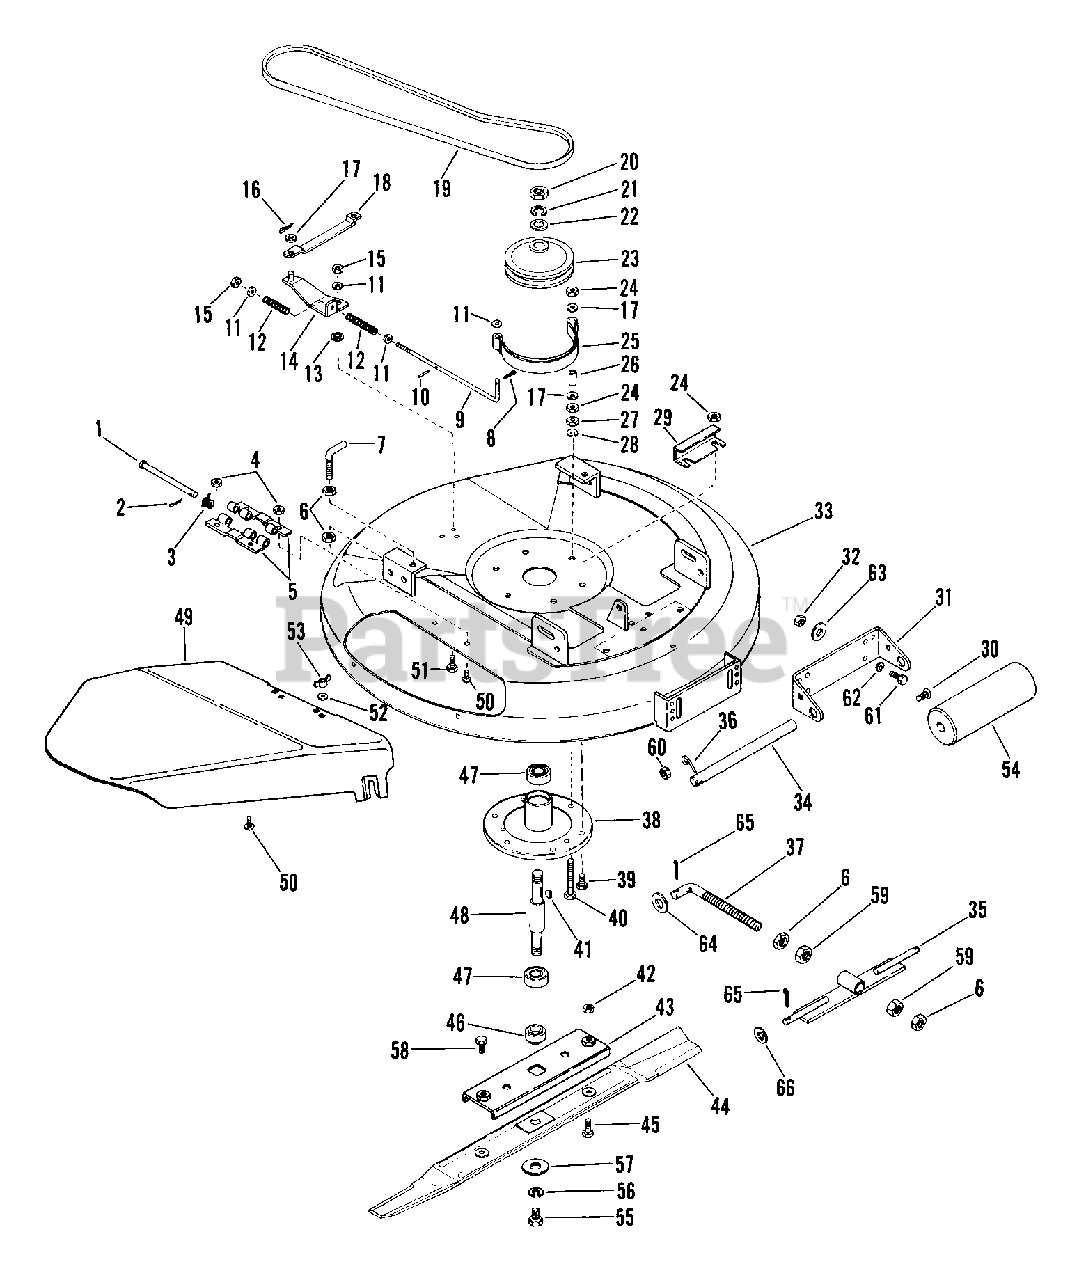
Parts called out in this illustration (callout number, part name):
1	CLEVIS PIN
2	PIN-COTR .09X.75 PL
3	SG-TORS .090X.37X.63
4	NUT-LK-CTR .250-20 PL
5	HINGE PLATE
6	NUT-JAM .50-13 PL
7	HANGER HOOK
8	PIN-COTR .06X.50
9	BRAKE ROD
10	PIN-ROLL .125X1.00
11	WSHR-FL-STL .323X.625X.062 PL
12	SG-COMP .057X.47X1.25
13	SPACER -FLANGED .325X.498X.318
14	BRAKE ACTUATOR
15	NUT-LK .312-18 GR A PL
16	PIN-COTR .12X1.0 PL
17	WSHR-FL-STL.406X.812X.065PL
19	V-BELT, 4L-RAW EDGE
20	NUT-JAM .75-10 PL
21	WSHR-LK .750X.188 MED PL
22	WSHR-FL-STL .755X1.250X.125
23	MOWER SHEAVE
24	NUT-LK-CTR .375-16 GR A PL
25	BRAKE BAND
26	SPACER .386X.502X1.060
27	NUT-HEX .375-16
28	WSHR-LK .375X.115 HVY PL
29	BRAKE BAND SUPPORT
30	BLT-RDHDSQNK .25-20X.75
31	ROLLER CLEVIS
32	NUT-HEX .312-18
33	32" MOWER PAN SERVICE ASSEMBLY
33	32" MOWER PAN ASSEMBLY
34	ROLLER SHAFT
35	ADJUSTMENT PLATE
37	ADJUSTMENT LINK
38	SPINDLE HOUSING
39	BLT-HEX .38-16X.75 PL GR5
40	BLT-HEX .38-16X3.00 PL GR5
41	KEY-WDRF .188X.75X.313 SAE 9
42	NUT-LK TOP .375-16 GR C YWZC
43	BLADE TRAY WELDMT
44	32" BLADE
45	BLT-HEX .38-16X1.00 PL GR5
47	BRG-BALL .750X1.781X.61
48	SPINDLE SHAFT
49	32" DEFLECTOR W/DECAL
50	BLT-RDHDSQNK .25-20X.62 PL
51	BLT-HEX .31-18X.75 PL GR5
52	WSHR-FL-STL .328X.875X.062 PL
53	NUT-WING W/INSERT .312 - 18
55	BLT-HEX .44-20X1.75 PL GR5
56	WSHR-LK .438X.133 HVY
57	WSHR-FL-STL .505X1.140X.250
58	BLT-HEX .38-24X.75 PL GR5
59	NUT .50-13 PL
60	NUT-LK-FLG .250-20 PL
61	BLT-HEX .31-18X1.00 PL GR 2
62	WSHR-LK .313X.078 PL MED
63	WSHR-FL-STL.344X.688X.065PL
64	WSHR-FL-STL .505X.880X.072 PL
65	PIN-COTR .12X1.0 PL
66	WSHR-FL-STL .531X1.062X.095 PL
